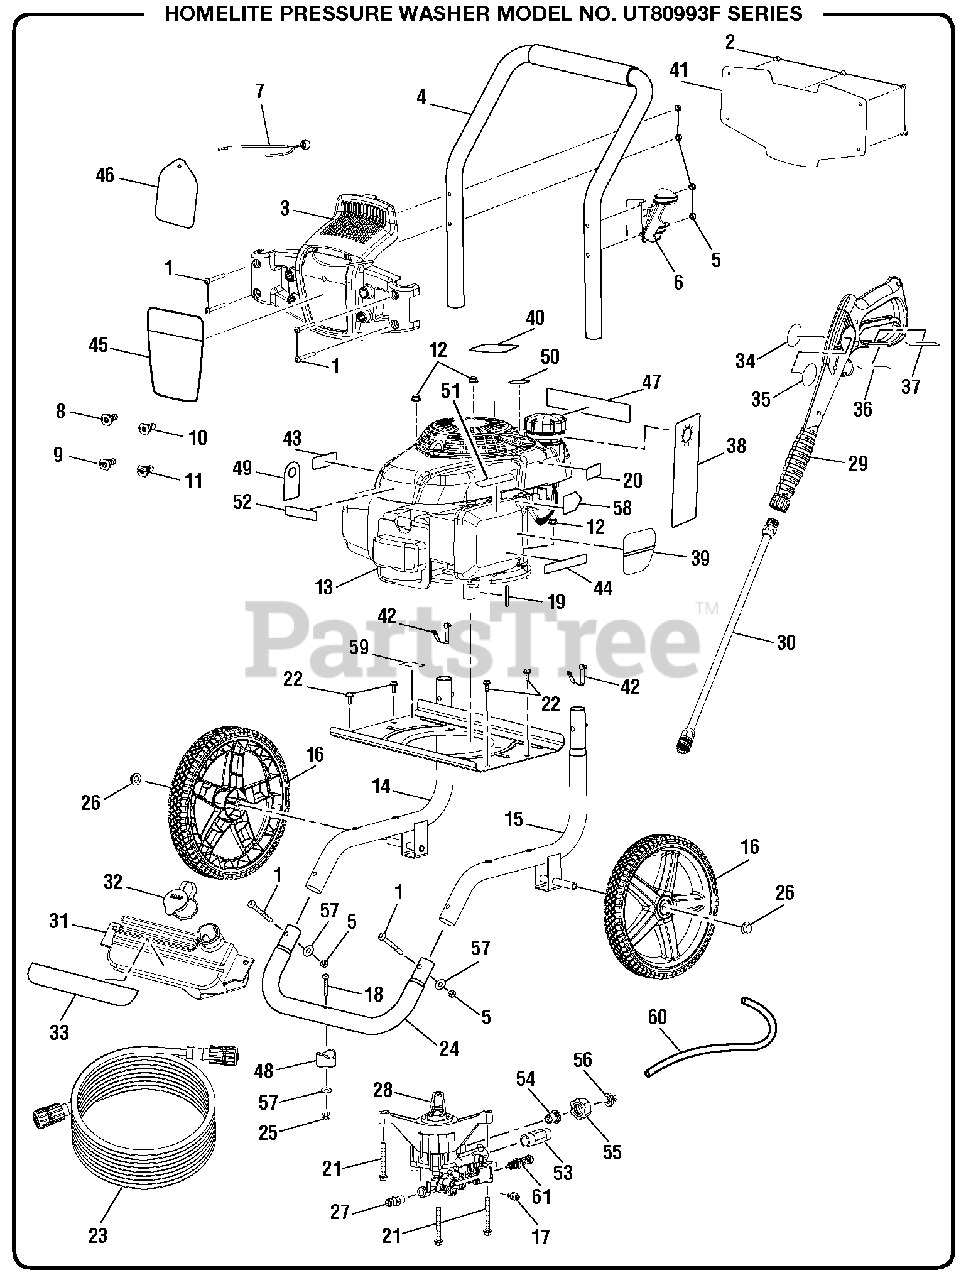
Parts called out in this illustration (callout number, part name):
1	Screw (M6 x 48 mm, T30 Torx Hd.)
2	Screw (#6-20)
3	Hose and Nozzle Holder
4	Handle w/Foam
5	Lock Nut (M6)
6	Wand Holder
7	Bungee Cord Assembly
8	40deg Nozzle
9	Soap Nozzle
10	25deg Nozzle
11	0deg Nozzle
12	Flange Nut (M8 x 1.25)
13	Engine (Honda GCV 160, 160cc OHC Vertical)
14	Main Frame Assembly A
15	Main Frame Assembly B
16	Wheel
17	Detergent Suction Kit
18	Screw (1/4-20 x 1.85 in., T30 Torx Hd.)
19	Output Shaft Key (40 mm)
20	Do Not Mix Label
21	Bolt (M8 x 60 mm, Flange Hd.)
22	Bolt (M6 x 16 mm)
23	Hose (25 ft., 3100 psi)
24	Front Frame
25	Lock Nut (1/4-20)
26	Push Cap Nut (1/2 in.)
27	Thermal Release Valve
28	Pump
29	Trigger Handle Assembly
30	Extension Wand
31	Soap Tank
32	Soap Tank Cap
33	Soap Dilution Label
34	Label (Wand Logo)
35	Label (Wand Warning)
36	Warning Label (Fr/Sp)
37	Label (Wand Rating)
38	Danger Hangtag
39	Engine Control Label
40	Combustion Label
41	Quick Start Panel
42	Lock Button w/Spring Clip
43	Hot Surface Label
44	EMC Label
45	Performance Label
46	Nozzle Hangtag
47	Danger Label
49	Dipstick Hangtag
50	No E85 Label
51	Inquiries Label
52	Honda Brand Label
53	Outlet Tube
54	Inlet Filter Connector
56	Filter Screen (Pump Inlet)
57	Washer (1/4 in.)
58	Engine On/Off Label
59	Oil Fill Location Label
60	Chemical Siphon Tube
61	Unloader Valve Assembly
